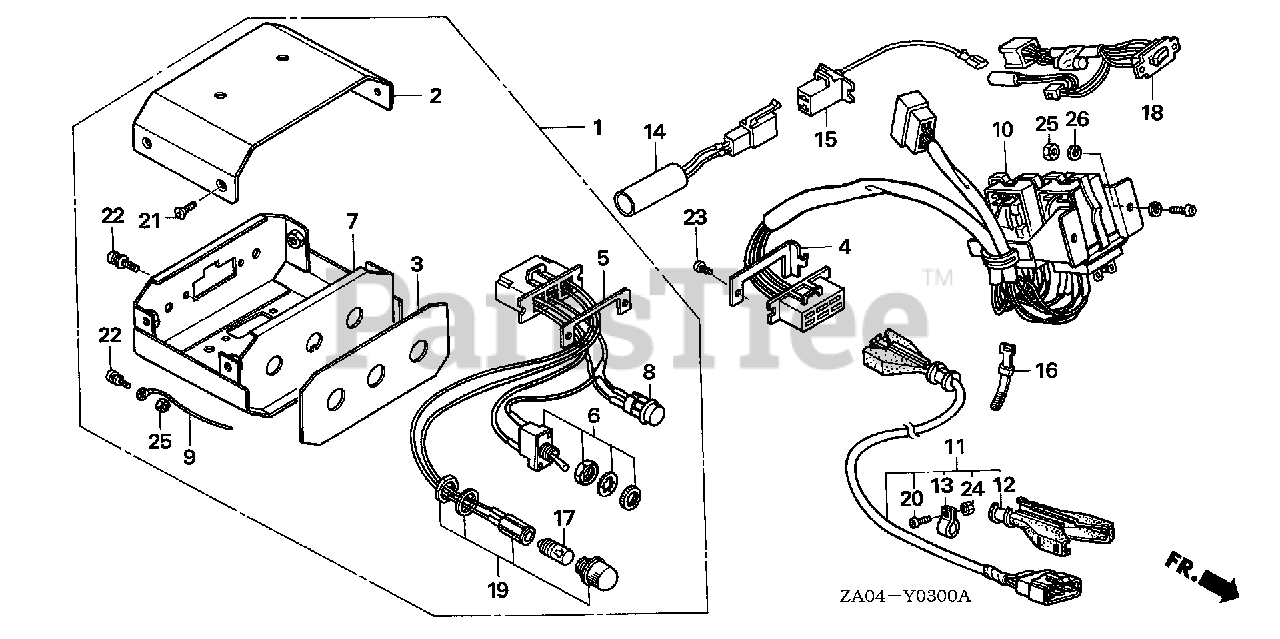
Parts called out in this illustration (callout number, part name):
1	BOX ASSY,SW*R280*
2	COVER (UPPER) *R8* (BRIGHT RED) Use up to Frame SN 1110009.
2	COVER (UPPER) *R280* Use from Frame SN 1110010.
3	PANEL, FR.
4	HOLDER, CONNECTOR (6P)
5	PLATE, CONNECTOR SETTING
6	SWITCH, TOGGLE
7	CASE, SWITCH
8	SWITCH, PUSH
9	WIRE, GROUND
10	RELAY ASSY.
11	CABLE, REMOTE CONTROL (10MM)
12	COVER, CONNECTOR
13	BAND
16	BAND B1, CABLE Use up to Frame SN 1001879.
17	BULB (24V2W)
19	HOLDER, LAMP
20	SCREW, PAN (3X12)
21	SCREW, FLAT (4X8) Use from Frame SN 1001725.
22	SCREW-WASHER (4X12)
23	SCREW, TAPPING (4X10)
24	NUT, HEX. (3MM)
25	NUT, HEX. (4MM)
26	WASHER, SPRING (4MM)
